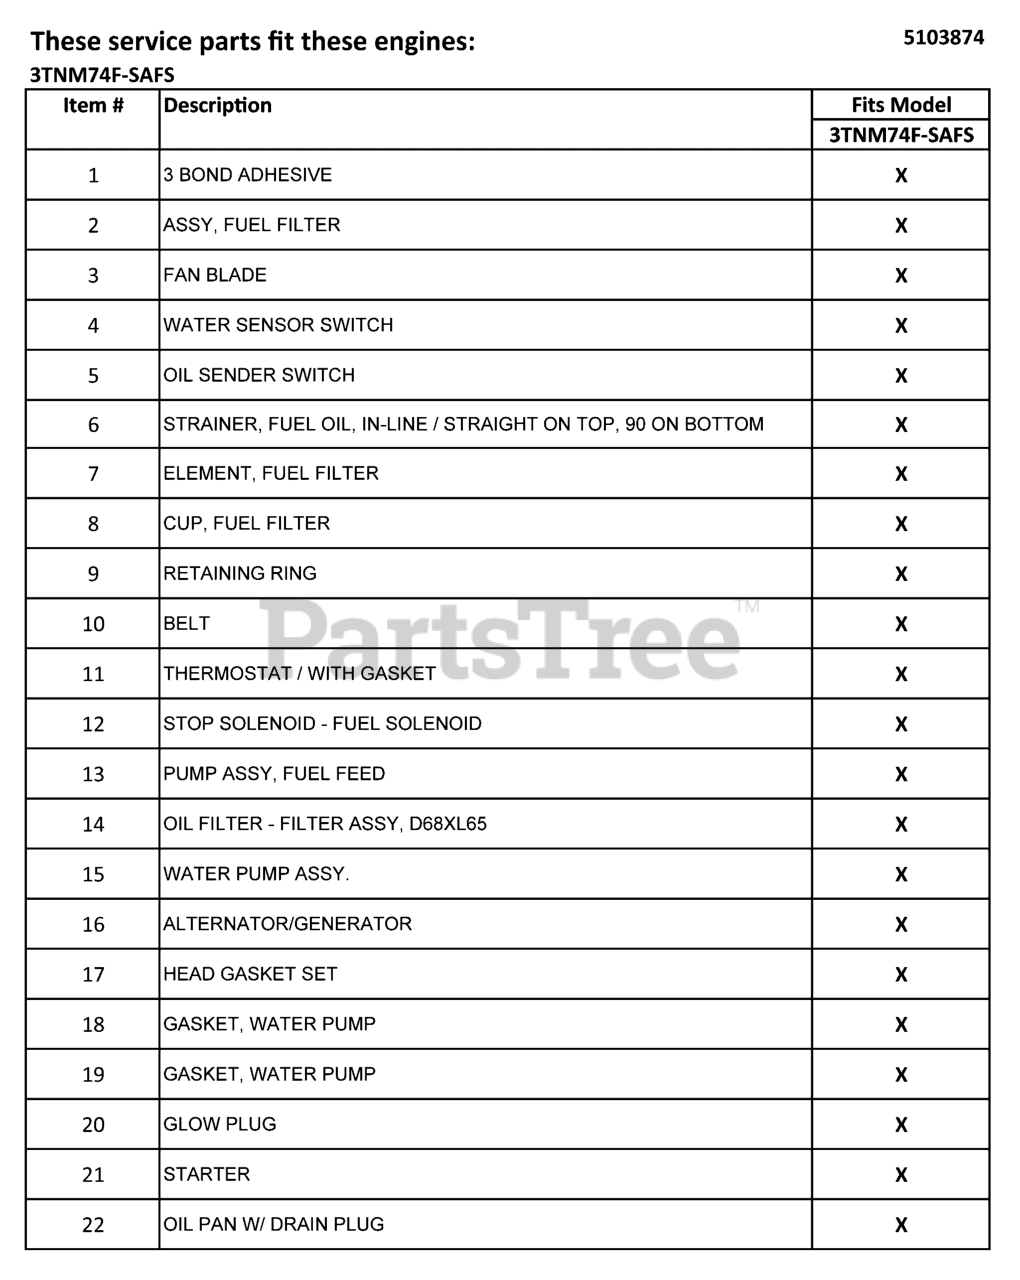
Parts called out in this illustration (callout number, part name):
1	3 BOND ADHESIVE
2	ASSY, FUEL FILTER
3	FAN BLADE
4	WATER SENSOR SWITCH
5	OIL SENDER SWITCH
6	STRAINER, FUEL OIL, IN-LINE / STRAIGHT ON TOP, 90 ON BOTTOM
7	ELEMENT, FUEL FILTER
8	CUP, FUEL FILTER
9	RETAINING RING
10	BELT
11	THERMOSTAT / WITH GASKET
12	STOP SOLENOID - FUEL SOLENOID
13	PUMP ASSY, FUEL FEED
14	OIL FILTER, 24HP YANMAR 3TNM72-AMW - NET
15	WATER PUMP ASSY.
16	ALTERNATOR/GENERATOR
17	HEAD GASKET SET
18	GASKET, WATER PUMP
19	GASKET, WATER PUMP
20	GLOW PLUG
21	STARTER
22	OIL PAN W/ DRAIN PLUG
